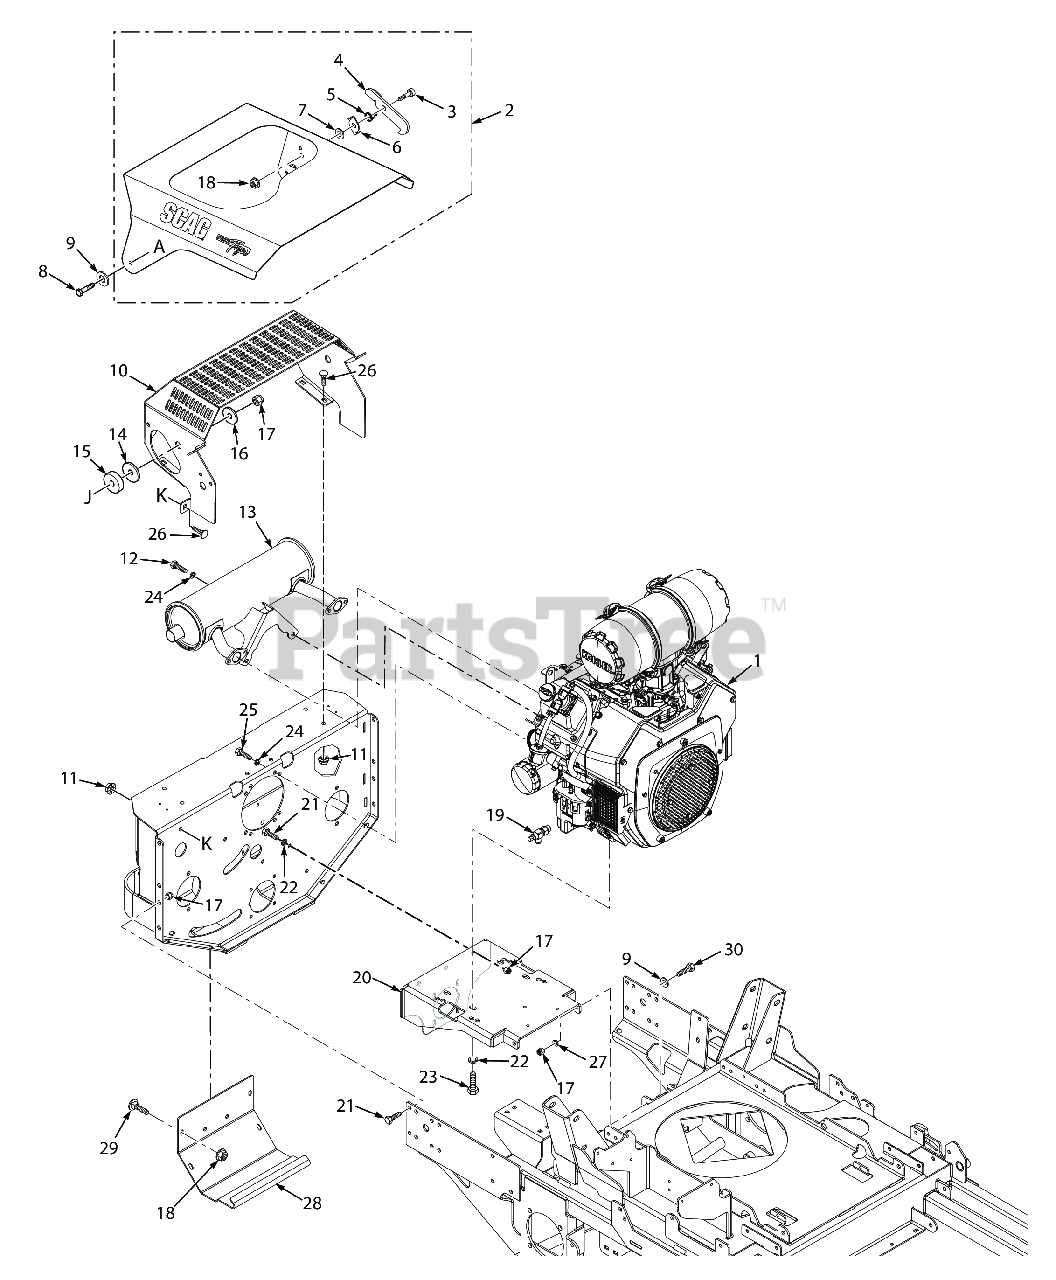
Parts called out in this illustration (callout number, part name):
1	Engine, Kohler 26CH-EFI (Available only through Kohler)
1	Engine, Briggs & Stratton V-Twin Air-Cooled (Avail. only through B & S)
1	Engine, 37BV-EFI - Briggs & Stratton
2	Hood Assy., STTII (EFI)
2	Hood Assy., STTII (FD750)
2	Hood Assy., STTII (37BV-EFI)
3	Bolt, Shoulder 5/16-18 x 1/2"
4	Latch, Hood
5	Spring, Hood Latch
6	Lock, Hood Latch
7	Flatwasher, 3/8 (.406 x .812 x .065)
8	Bolt, Hex Head 3/8-16 x 1-3/4" (Kohler EFI)
9	Flatwasher, 3/8" Special (.391 x .938 x .105)
10	Guard, Muffler
11	Bolt, Hex Head Serrated Flange 1/4-20 x 3/4"
12	Bolt, Hex Head 3/8-16 x 1"
13	Muffler, 26EFI - Kohler
13	Muffler, 35BV - Briggs & Stratton
13	Muffler, 37BV-EFI - Briggs & Stratton
14	Disc, Anti-Friction
15	Spacer, Hood
16	Flatwasher, 3/8-.406 x 1-1-1/2 x 7 Gauge
17	HEX NUT, ELASTIC STOP LOCK, 3/8-16
18	Nut, Serrated Flange 5/16-18 (Right Front Engine Mounting, Briggs and Kohler Only)
19	Oil Drain, 35BV & 37BV-EFI - Briggs & Stratton
20	Plate Weldment, Engine Mounting
21	Bolt, Hex Head, 3/8-16 x 1 Gr. 5
22	Lockwasher, 3/8" Spring, Kawasaki FX / FS
23	Bolt, Hex Head 3/8-16 x 1-3/4" (Kohler EFI)
23	Bolt, Hex Head 5/16-18 x 2-1/2" (x3) (35BV & 37BV-EFI)
23	Bolt, Hex Head 5/16-18 x 2-1/2" (35BV & 37BV-EFI)
24	Lockwasher, 3/8" Spring, Kawasaki FX / FS
25	Bolt, Hex Head, 3/8-16 x 1 Gr. 5
26	Bolt, 5/16-18 x .75 RHSN Carriage
27	Lockwasher, 3/8" Spring, Kawasaki FX / FS
28	Cover, Rear
29	Bolt, 5/16-18 x .75 RHSN Carriage
30	Bolt, Hex Head 3/8-16 x 1-1/4", Kawasaki FX / FS
